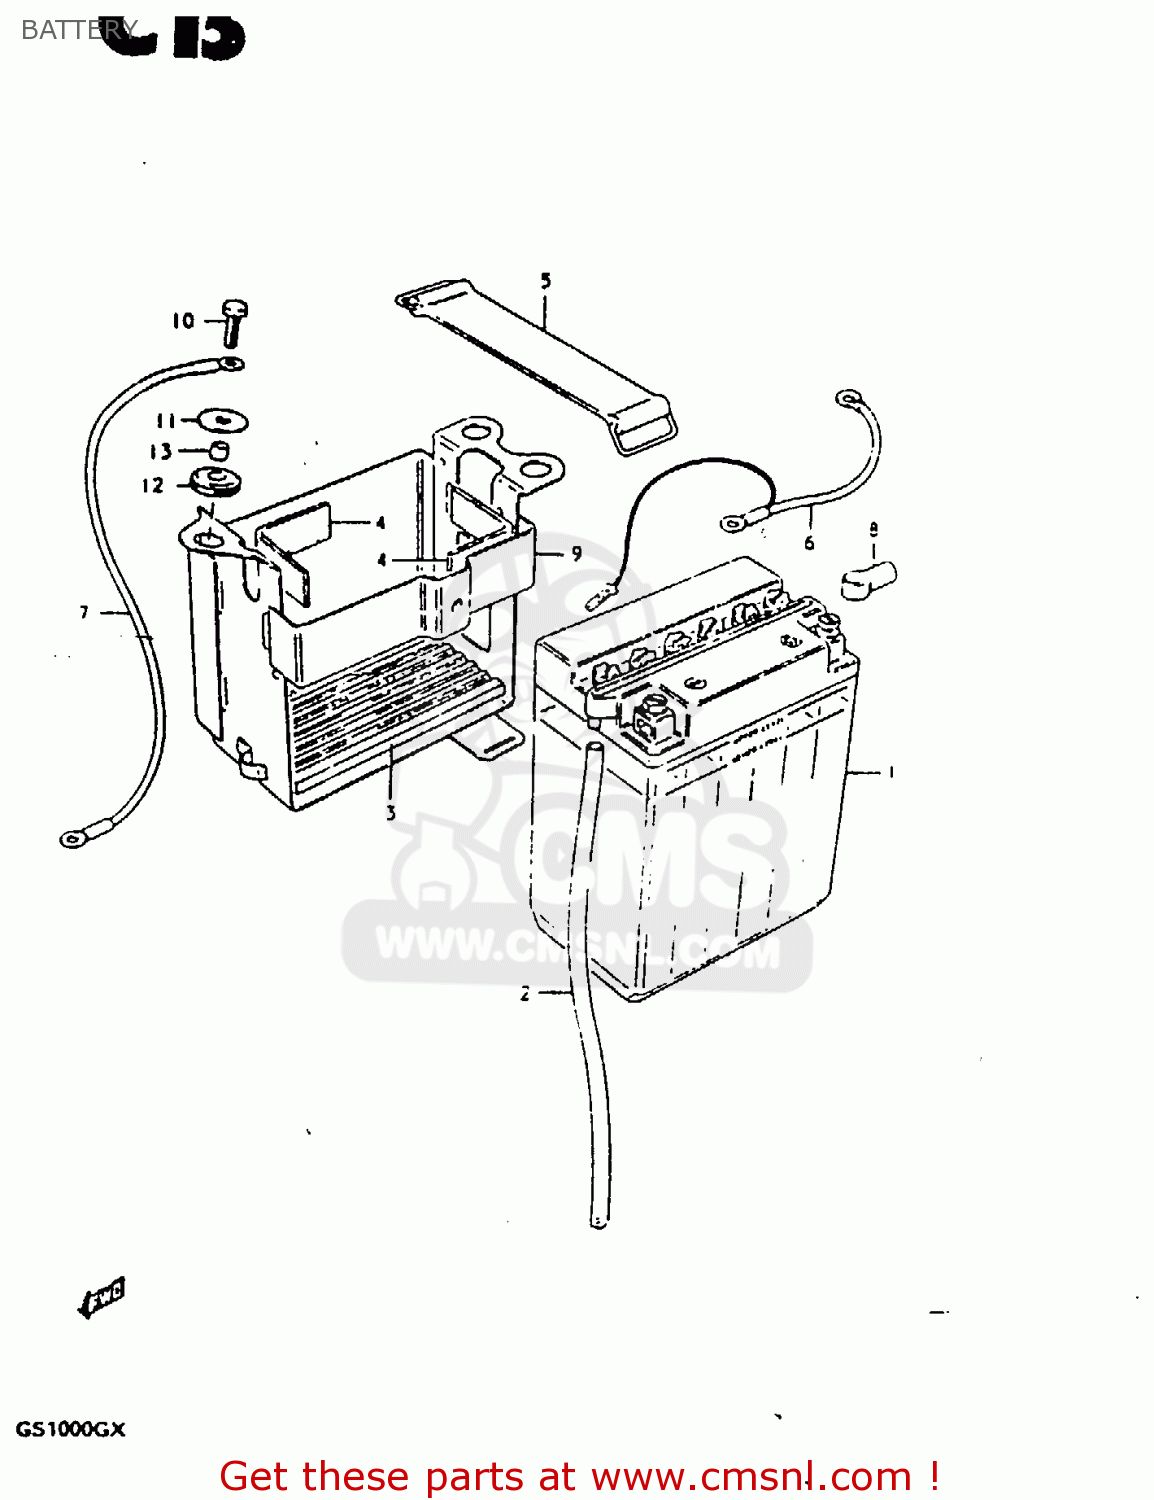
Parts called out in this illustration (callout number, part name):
1	BATTERY ASSY (12V)
2	HOSE,BATTERY EXHAUST
3	PROTECTOR,BATTERY
4	PROTECTOR(20X90)X4
5	BAND
6	WIRE,BATTERY PLUS
7	LEAD WIRE,BATTERY(-)
8	CAP,TERMINAL
9	HOLDER,BATTERY
10	BOLT, UPPER
11	WASHER(6,5X22X1.6)
12	CUSHION
13	SPACER(6.2X8.3X5.7)
